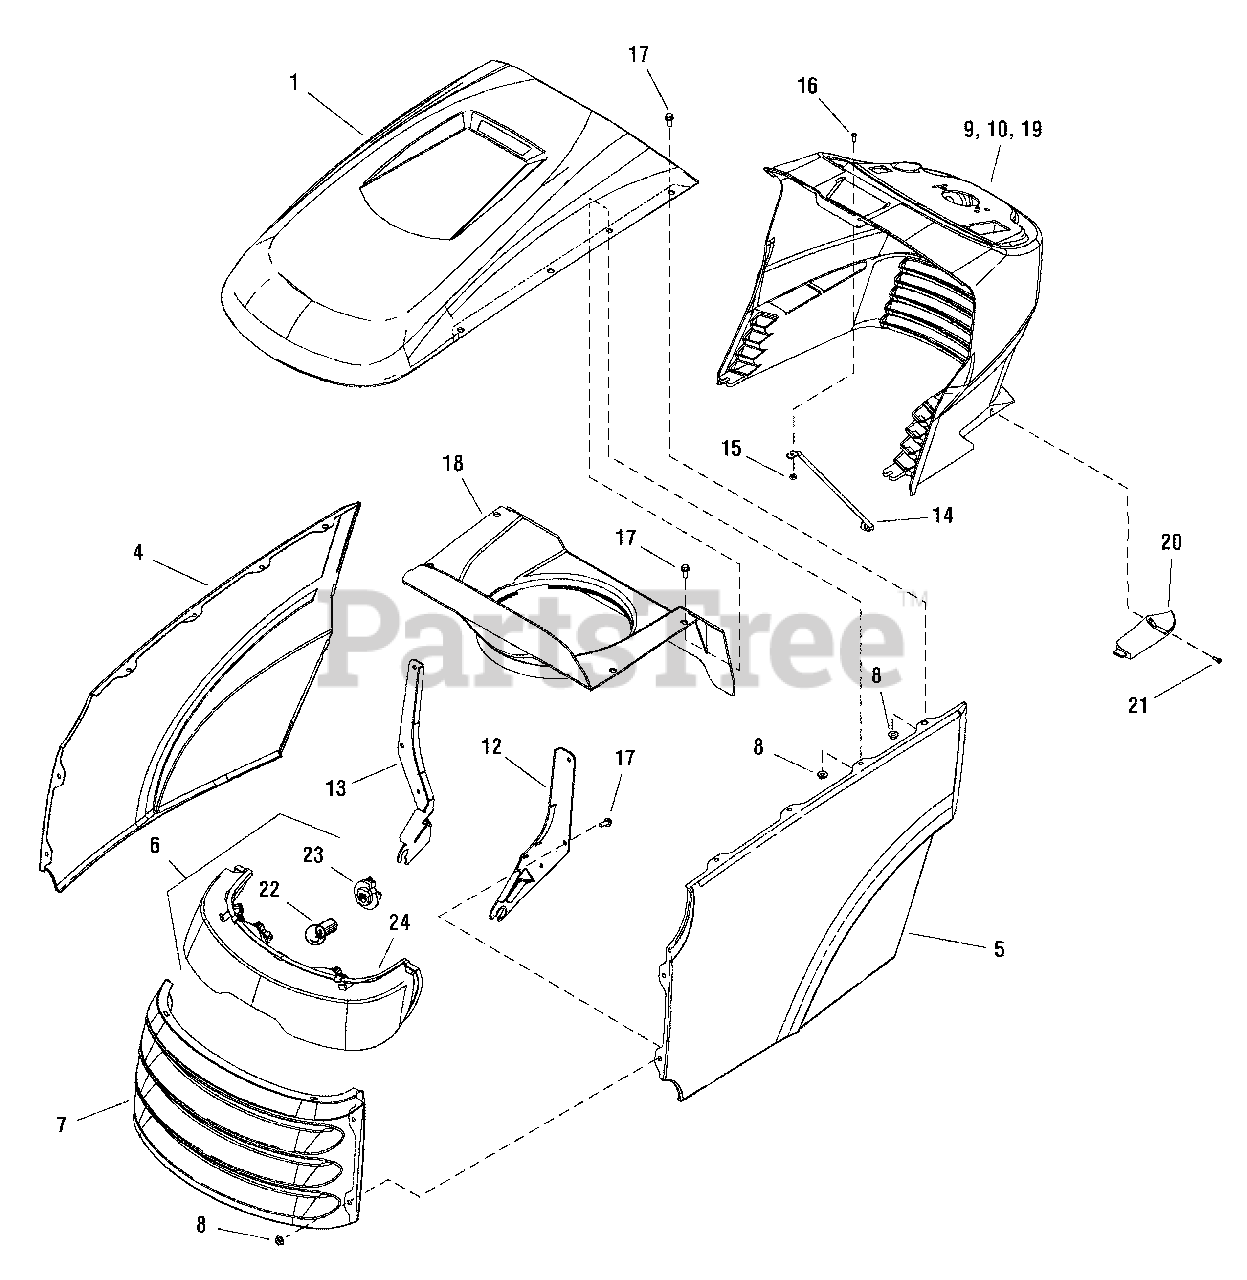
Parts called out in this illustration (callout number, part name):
1	HOOD, W/Scoop
4	PANEL, R.H. Side
5	PANEL, L.H. Side
6	HEADLIGHT ASSEMBLY
7	GRILLE
8	NUT, Hex Flange 1/4-20 Whiz Lock
9	DASHBOARD
10	DASHBOARD, W/Hydraulic Lift Slot
12	HINGE, Hood L.H.
13	HINGE, Hood R.H.
14	ROD, Dash Support
15	NUT, Hex Lock 10-24 w/Nylon Insert
16	SCREW, Hex Washer Head Slot #10-24 x .625
17	SCREW, Hex Whiz Lock Flange 1/4-20 x 5/8
18	DUCT, Air Inlet
19	DASHBOARD, w/Buzzer Hole
20	COVER, Dash
21	SCREW, Pan Head Torx #8-16 x 1/2 Plastite
22	BULB, Headlight (#1156)
23	SOCKET ASSEMBLY, Seal
24	REFLECTOR, Headlight
